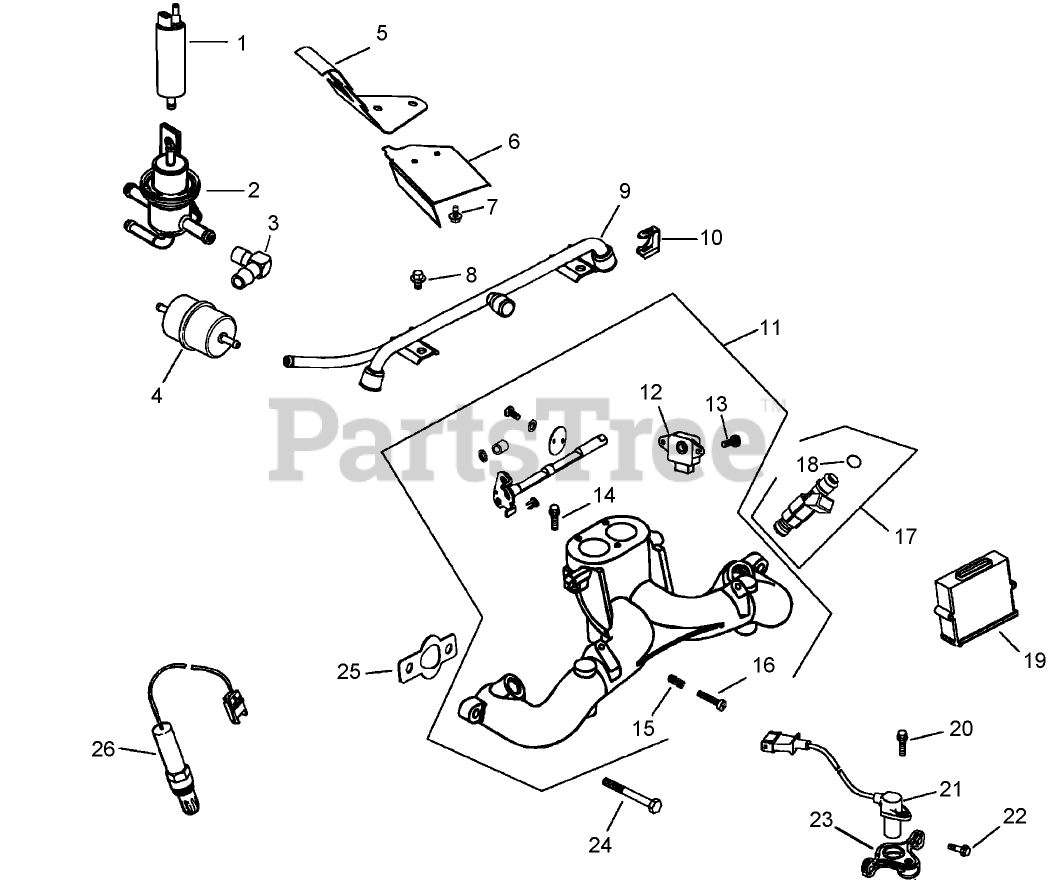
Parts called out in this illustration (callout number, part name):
1	Fuel Pump ASM (Includes 24 050 06-S)
2	Fuel Pressure Regulator ASM
3	Connector-Hose
4	Filter-Fuel
5	Baffle-Valley
6	Deflector-Air
7	SCREW-HHFTF (M5X.80X10)
8	Screw-HF (M6x1.0x10)
9	Rail-Fuel
10	Clip-Injector, Fuel
11	Intake Manifold ASM (Includes 18-22 and 25 454 03-S
12	Sensor-Position,Throttle
13	Screw-Head, Pan
14	Screw-Set
15	Spring-Control, Speed
16	Screw-HH
17	Injector-Fuel (Includes 24)
18	O Ring-Injector, Fuel
19	Control Unit-Electronic (ECU)
20	Screw-HF
21	Sensor-Speed, Engine
22	SCREW-FLANGE, THREAD FORMING (M5X0.8X16)
23	Bracket-Sensor, Speed
24	Screw-HF
25	Gasket-Manifold, Intake
26	Sensor-Oxygen
